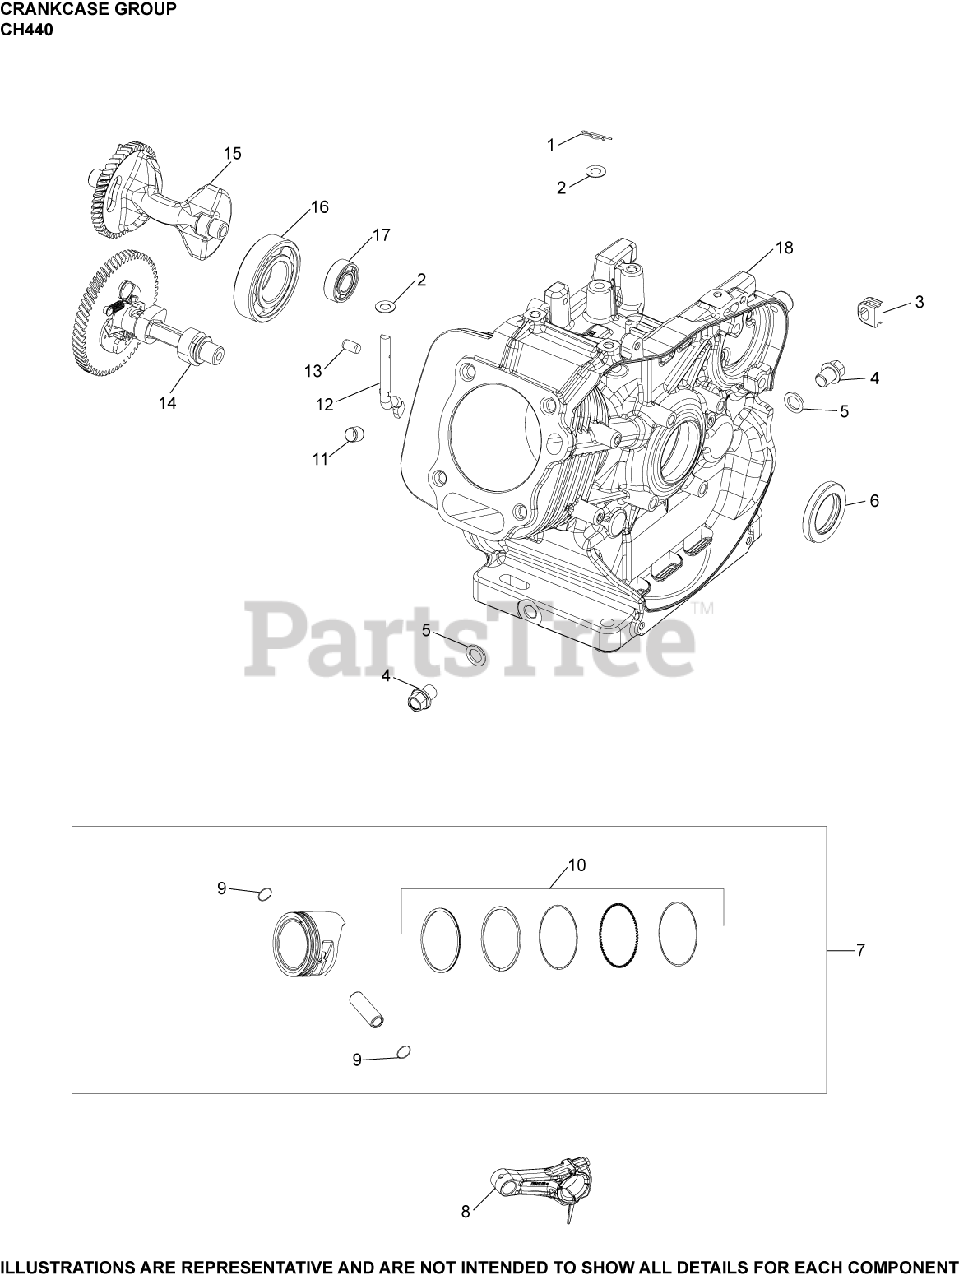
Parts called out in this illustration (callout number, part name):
1	CLIP, GOVERNOR SHAFT
2	WASHER, FLAT
3	GROMMET, CRANKCASE
4	KIT, DRAIN PLUG
5	WASHER, DRAIN PLUG
6	SEAL, CRANKSHAFT
7	KIT, PISTON (STD) (2.0mm Thick Top Ring) - USE 17 874 11-S
7	KIT, PISTON (0.25 O.S.)
7	KIT, PISTON (STD) (1.2 mm Thick Top Ring)
8	ROD, CONNECTING ASSEMBLY
9	RETAINER, PISTON
10	RING SET, PISTON (2.0 mm Thick Top Ring)
10	RING SET (0.25 O.S.)
10	RING SET, PISTON (1.2 MM Thick Top Ring)
11	PIN, DOWEL CYLINDER HEAD
12	SHAFT, GOVERNOR CROSS
13	PIN, DOWEL
14	CAMSHAFT ASSEMBLY
15	SHAFT, BALANCE
16	BEARING, CRANKSHAFT
17	BEARING, BALANCE SHAFT
18	CRANKCASE
